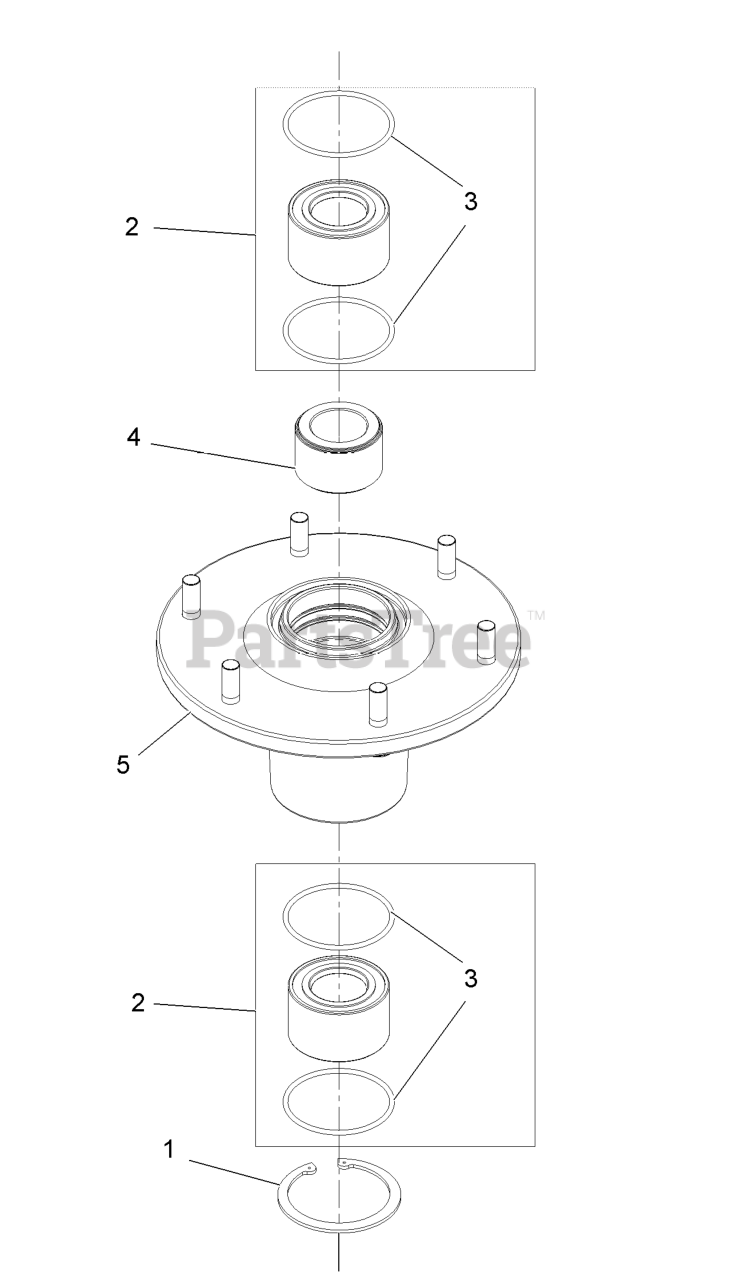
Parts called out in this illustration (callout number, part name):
1	RING-RETAINING
2	ASM, BEARING W/ORINGS
4	SPACER,BEARING
5	ASM,HOUSING W/STUDS
